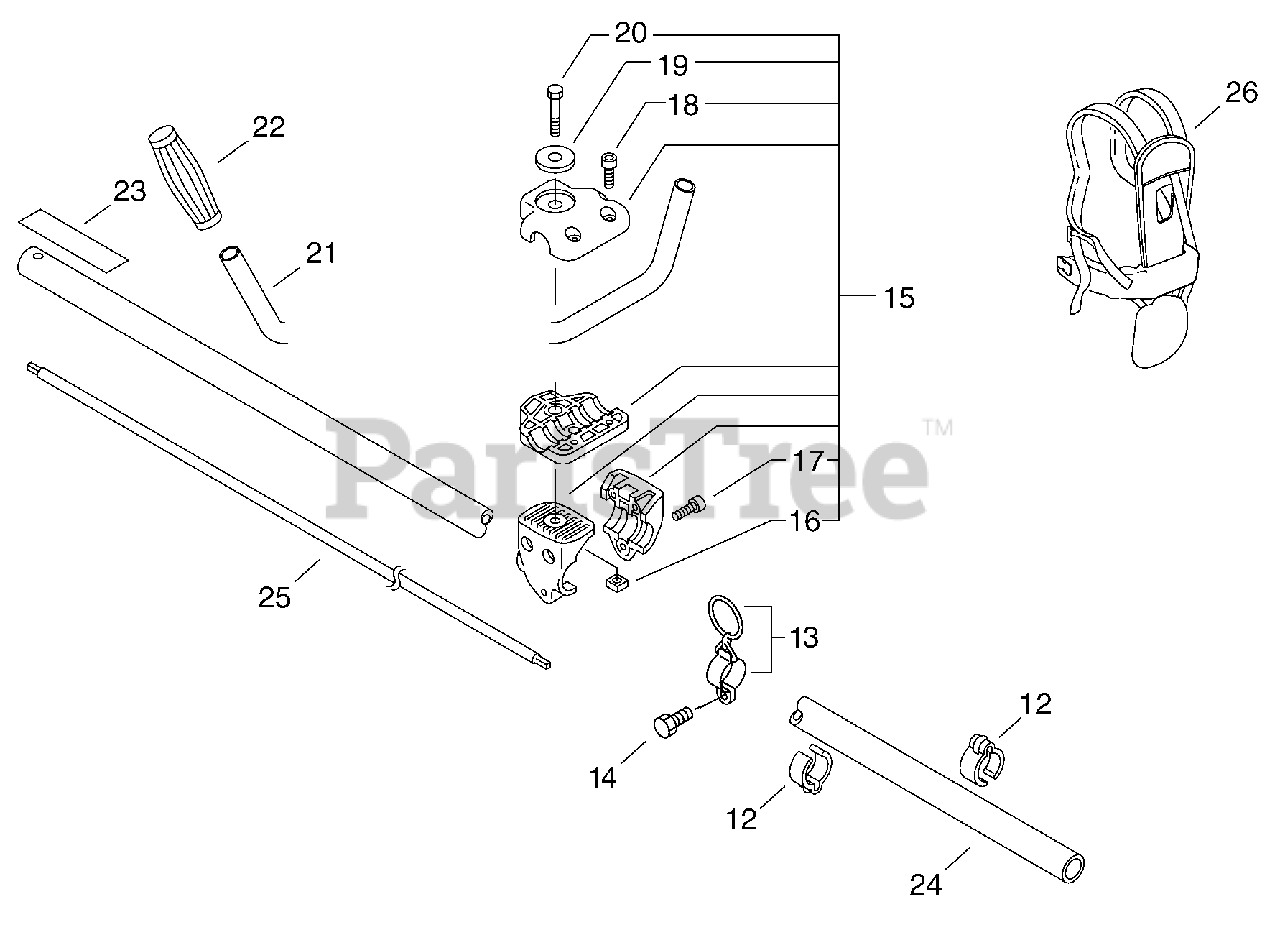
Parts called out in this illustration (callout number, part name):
12	CLIP, CABLE 25 MM
13	HANGER SET, HARNESS
14	BOLT 5×12
15	BRACKET KIT, HANDLEBAR
16	NUT 8×1.25
17	BOLT 5×30
18	BOLT 5×20
19	WASHER 8
20	BOLT 8×55
21	HANDLEBAR
22	GRIP, HANDLE
23	LABEL, CAUTION - ISO
24	MAIN PIPE ASSY 25×L= 1500
25	DRIVESHAFT
26	HARNESS, SHOULDER
